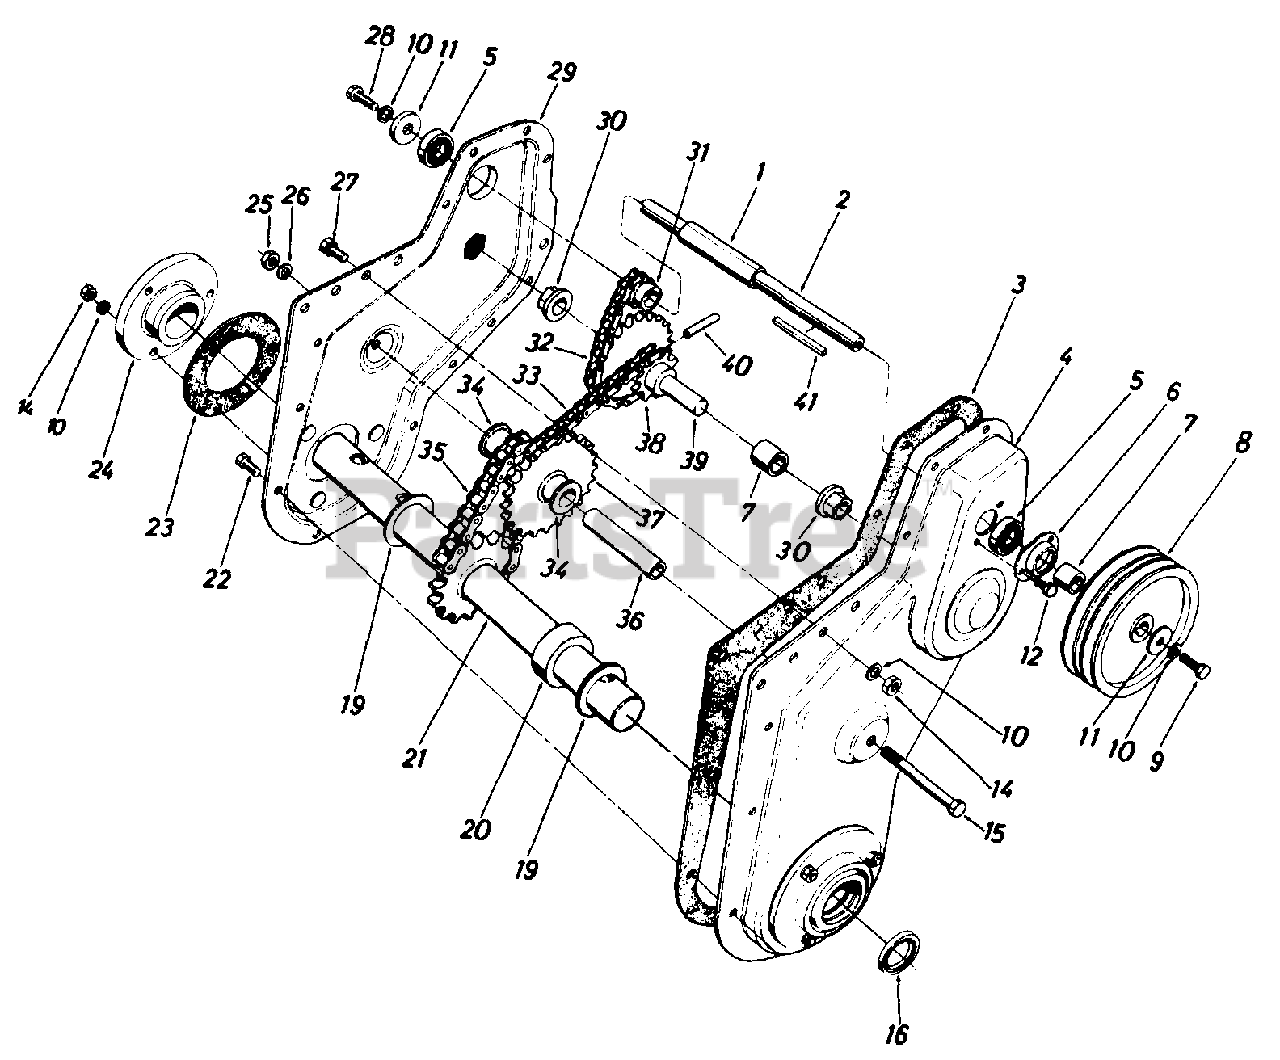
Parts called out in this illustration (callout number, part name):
1	Spacer .657 I.D. x .78 O.D. x 2.19
2	Jack Shaft
3	Gasket for Housing
4	Housing Half - L.H.
5	Ball Bearing .625 I.D. x 1.375 O.D.
6	Bearing Housing
7	Spacer .625 I.D. x .88 O.D. x 1.035
8	Chain Case Pulley 6.00" Dia.
9	Hex Bolt 5/16-18 x 1.00" Lg. Special
10	L-Wash. 5/16" Scr.
11	Fl-Wash. 5/16 I.D. x 1.125 O.D. x .125
12	Hex Self-Tap Scr. 1/4-20 x .50" Lg.
14	Hex Nut 5/16-18 Thd.
15	Hex Bolt 3/8-16 x 3.25" Lg.
16	Oil Seal 1" I.D. x 1.357 O.D.
19	Fl-Wash. 1.0" I.D. x 1.62 O.D. x .090
20	Spacer 1.0" I.D. x 2.0" O.D. x .68
21	Tine Shaft Ass'y.
22	Hex Self-Tap Scr. 1/4-20 x .50" Lg.
23	Gasket for Bearing Hsg.
24	Bearing Housing Ass'y.
25	Hex Nut 3/8-16 Thd.
26	L-Wash. 3/8" Scr.
27	Hex Sems Bolt 5/16-18 x 1.00" Lg.
28	Hex Bolt 5/16-18 x .62" Lg. Special
29	Housing Half - R.H.
30	Hex Flanged Bearing .630 I.D.
31	Sprocket 10 Teeth x .500 Pitch
32	#41 Chain 1/2" Pitch x 34 Links - Endless
33	#420 Chain 1/2" Pitch x 48 Links - Endless
34	Flange Bearing .626 I.D.
35	#50 Chain 5/8" Pitch x 28 Links - Endless
36	Sprocket Shaft
37	Sprocket Bearing Sleeve Ass'y.
38	Sprocket Sleeve Ass'y.
39	Sprocket Shaft
40	Spring Pin Spiral 1/4" Dia. x 1.5" Lg.
41	Sq. Key 3/16 x 1.50" Lg.
